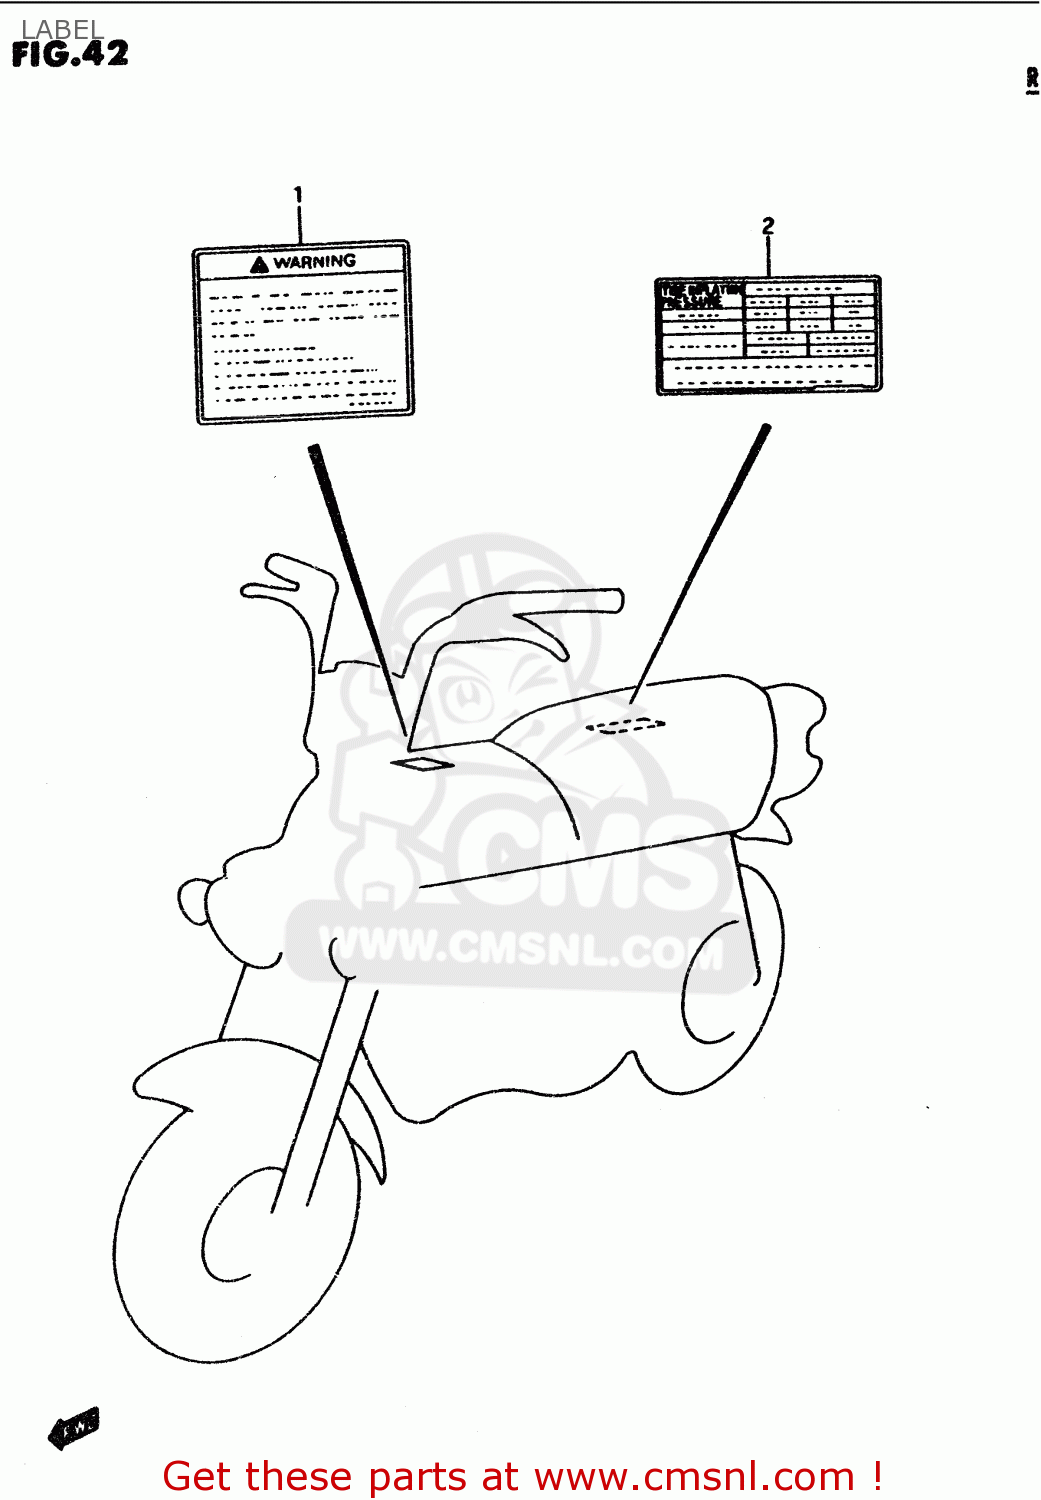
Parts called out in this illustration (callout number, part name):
1	LABEL
2	LABEL, TIRE AIR PRESSURE
3	MANUAL, OWNER'S
